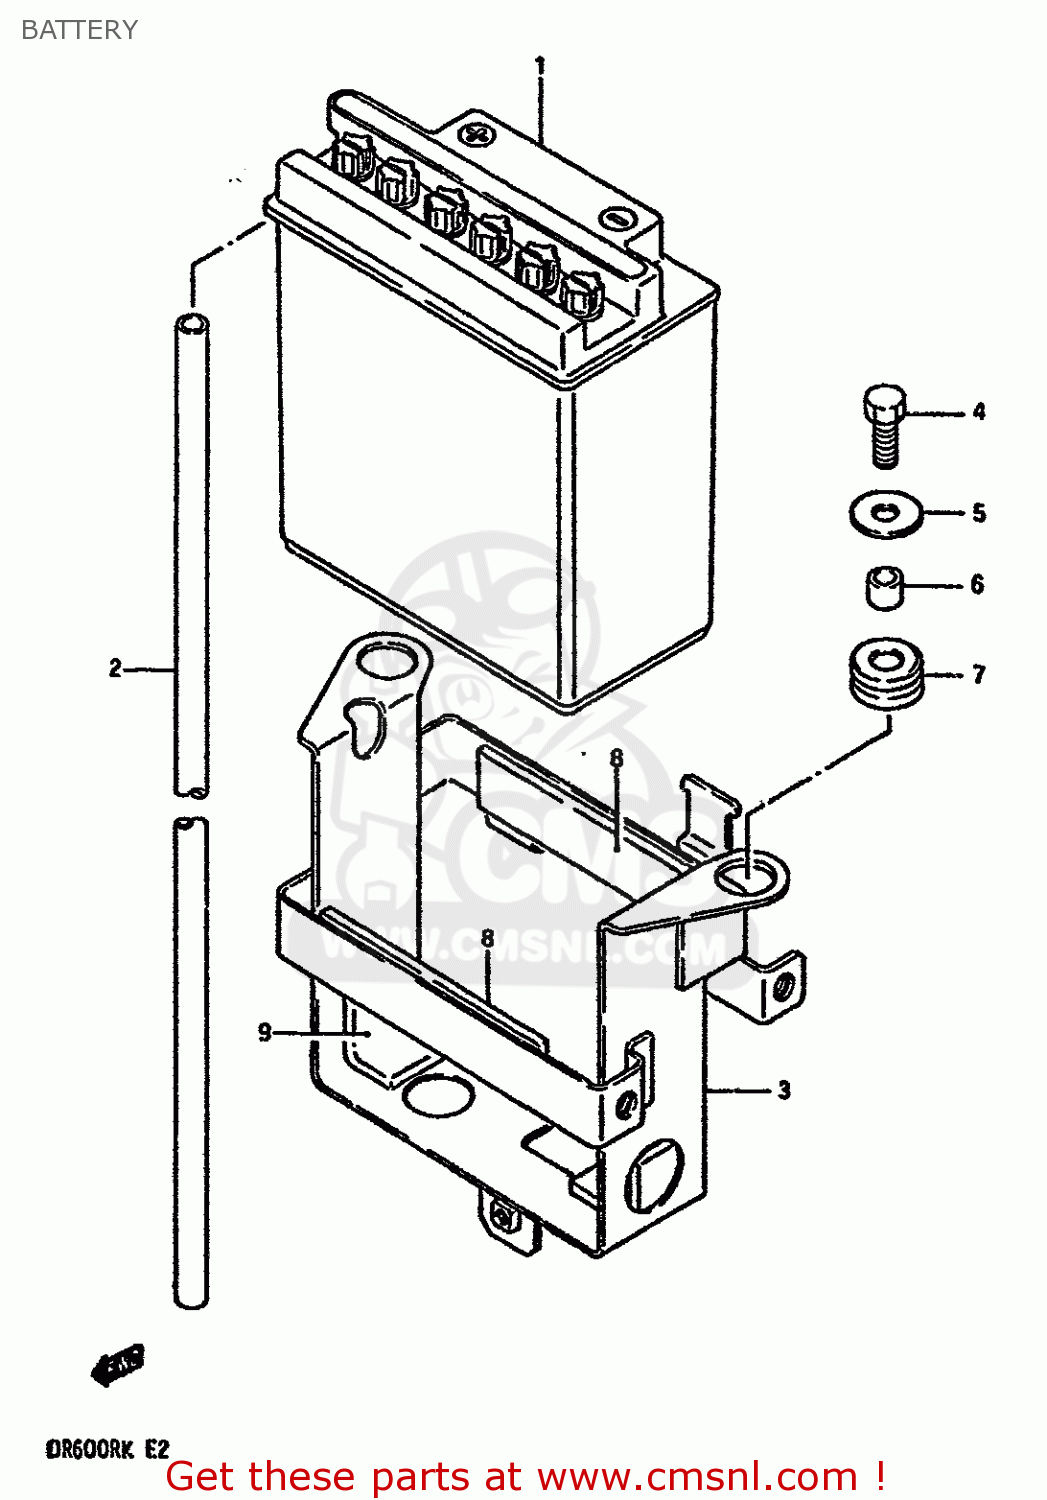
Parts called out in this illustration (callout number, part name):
1	BATTERY ASSEMBLY (12V)
2	HOSE,BATTERY EXHAUST
3	HOLDER,BATTERY
4	BOLT,M6X1X20
5	WASHER (6.5X20X1.2)
6	SPACER(6.1X9X7.5)
7	CUSHION
8	PROTECTOR,20X9
9	PROTECTOR(30X80X2)
